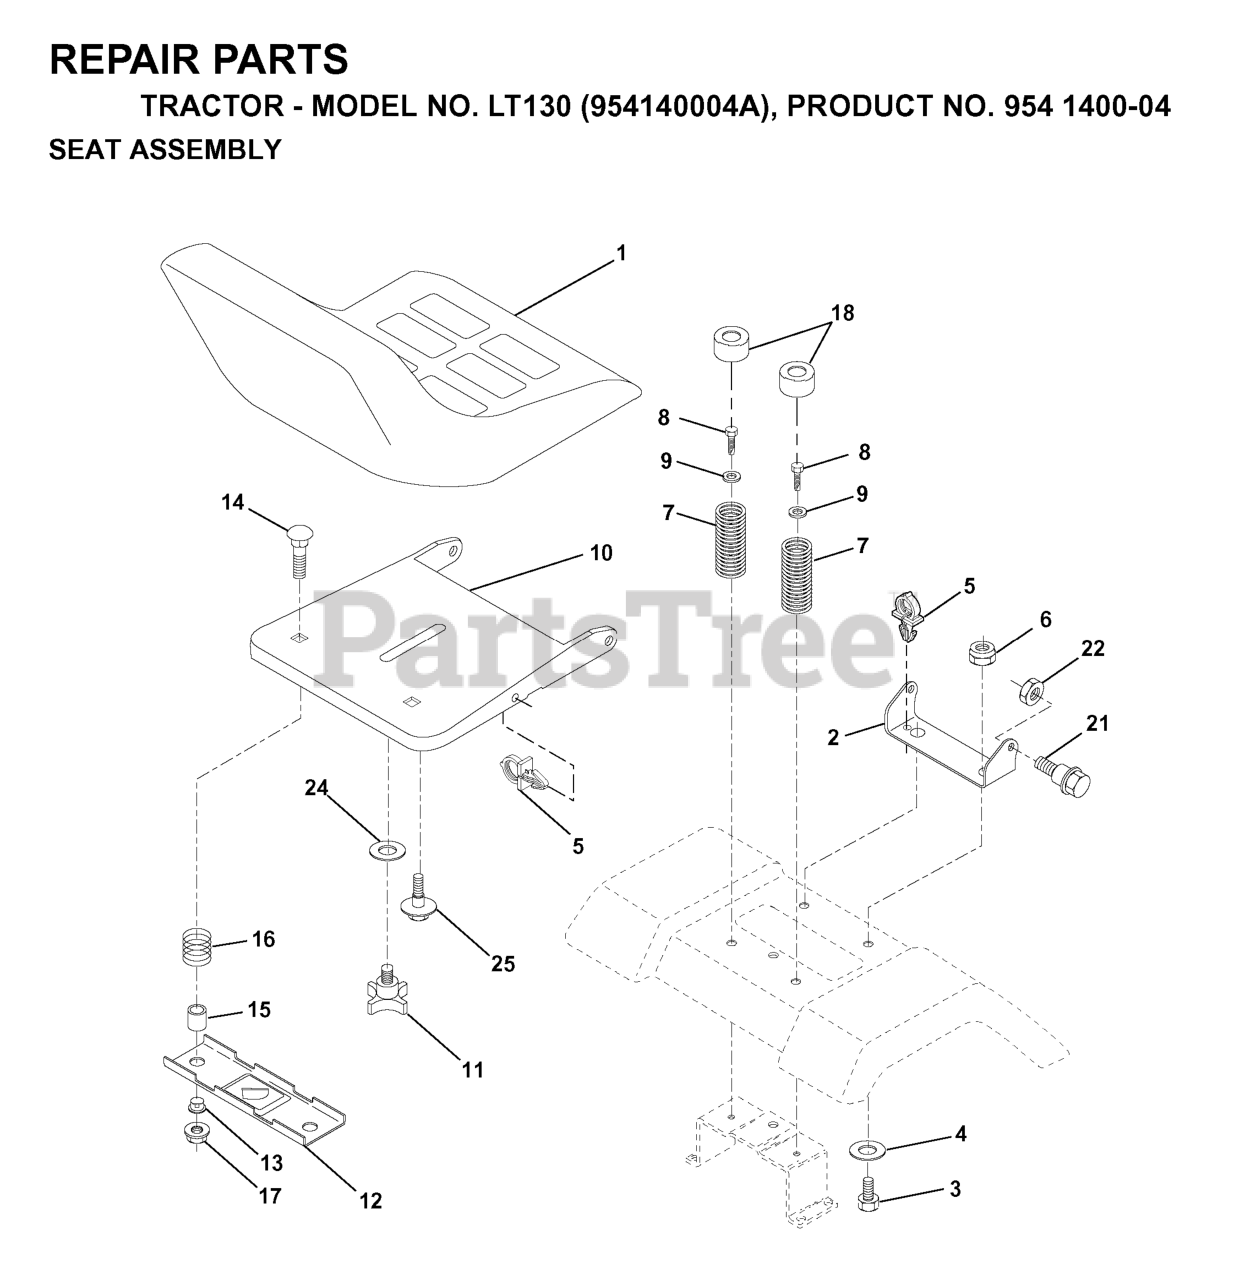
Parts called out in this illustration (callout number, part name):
1	SEAT
2	SEAT PIVOT BRKT
3	BOLT
6	NUT
7	SPRING COMPRESSION
8	SCREW GTV
9	WASHER
10	PAN, SEAT
11	KNOB 1/2" YT
12	BRKT SWITCH
14	Bolt Rdhd. Sht. Nk 1/4-20 x 1-3/8
15	SPACER SPLIT 28X.96
17	NUT T
18	CAP SPRING
21	BOLT SHOULDER 5/16-18
22	NUT.71038.31-18.HEX.NYLOCK
25	BOLT,SHOULD
